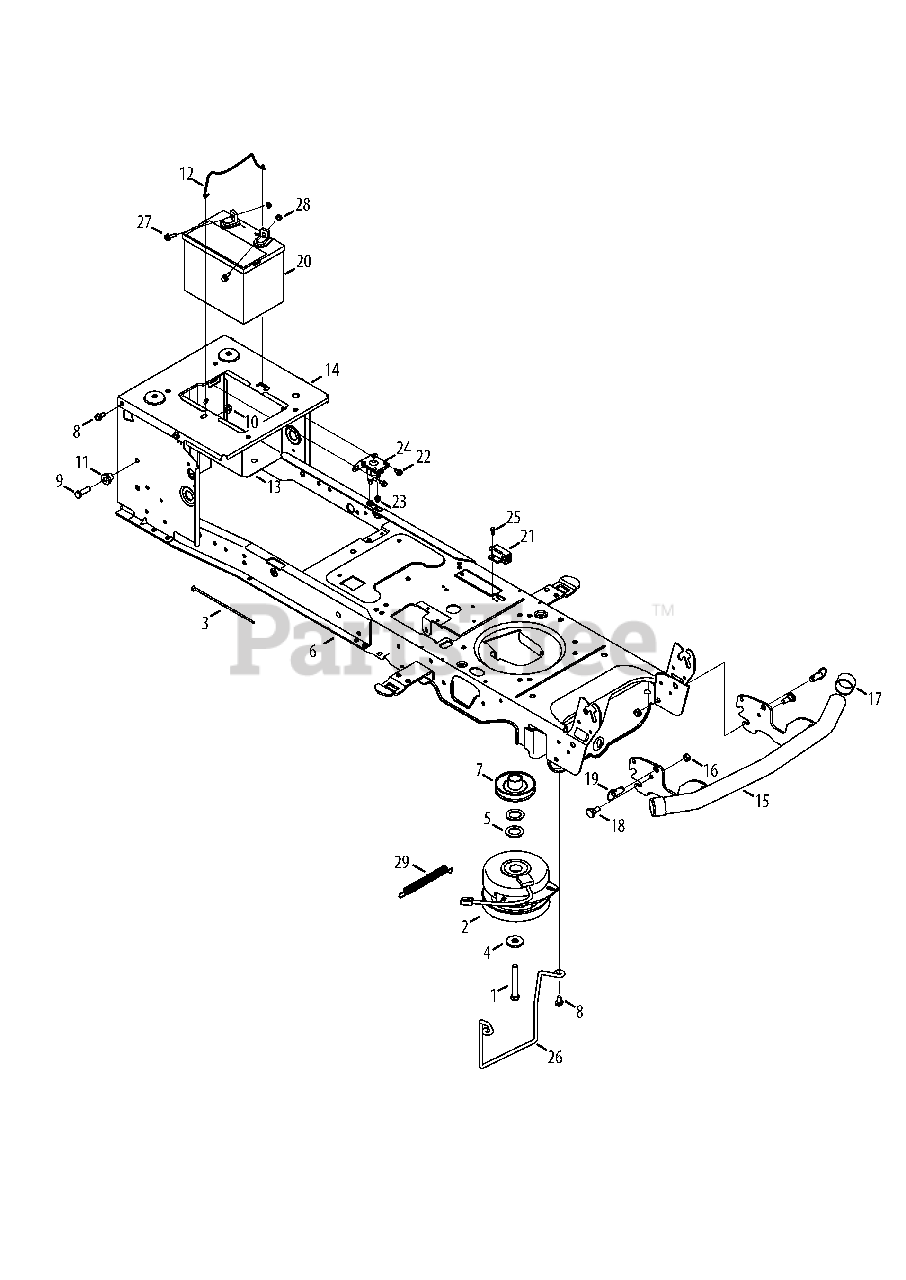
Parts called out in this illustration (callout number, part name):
1	Hex Head Screw, 7/16-20:3.50
2	Electric PTO Clutch
2	Clutch Harness Wire 11.625"
3	Cable Tie, 3/16 x .05 x 7.4
4	Washer, Flat, .450 x 1.25 x .164
5	Flat Washer, 1.031 x 1.620 x .095
6	Frame
7	Electric PTO Engine Pulley
8	Taptite Screw, 5/16-18:.750
9	Hex Head Screw, 3/8-16:1.25
10	Flangelock Nut, 3/8-16
11	Shoulder Spacer, .38 x 1.0 x .70
12	Battery Holder Rod
13	Battery Tray
14	Seat Frame Bracket
16	Hexlock Nut, 3/8-16
17	Bumper Cap
18	Shoulder Bolt, .496 x .336
19	Quick Release Pin
20	Battery
21	Interlock Switch
22	Taptite Screw, 1/4-20:0.375
23	Flangelock Nut, 1/4-20
24	Solenoid, 12 V
25	Shoulder Screw, #10-32:.500
26	Belt Keeper Rod
27	Hex Head Flange, 1/4-20:.75
28	Sems Nut, 1/4-20
29	Spr, Extn, .56 Dia X 5.52
